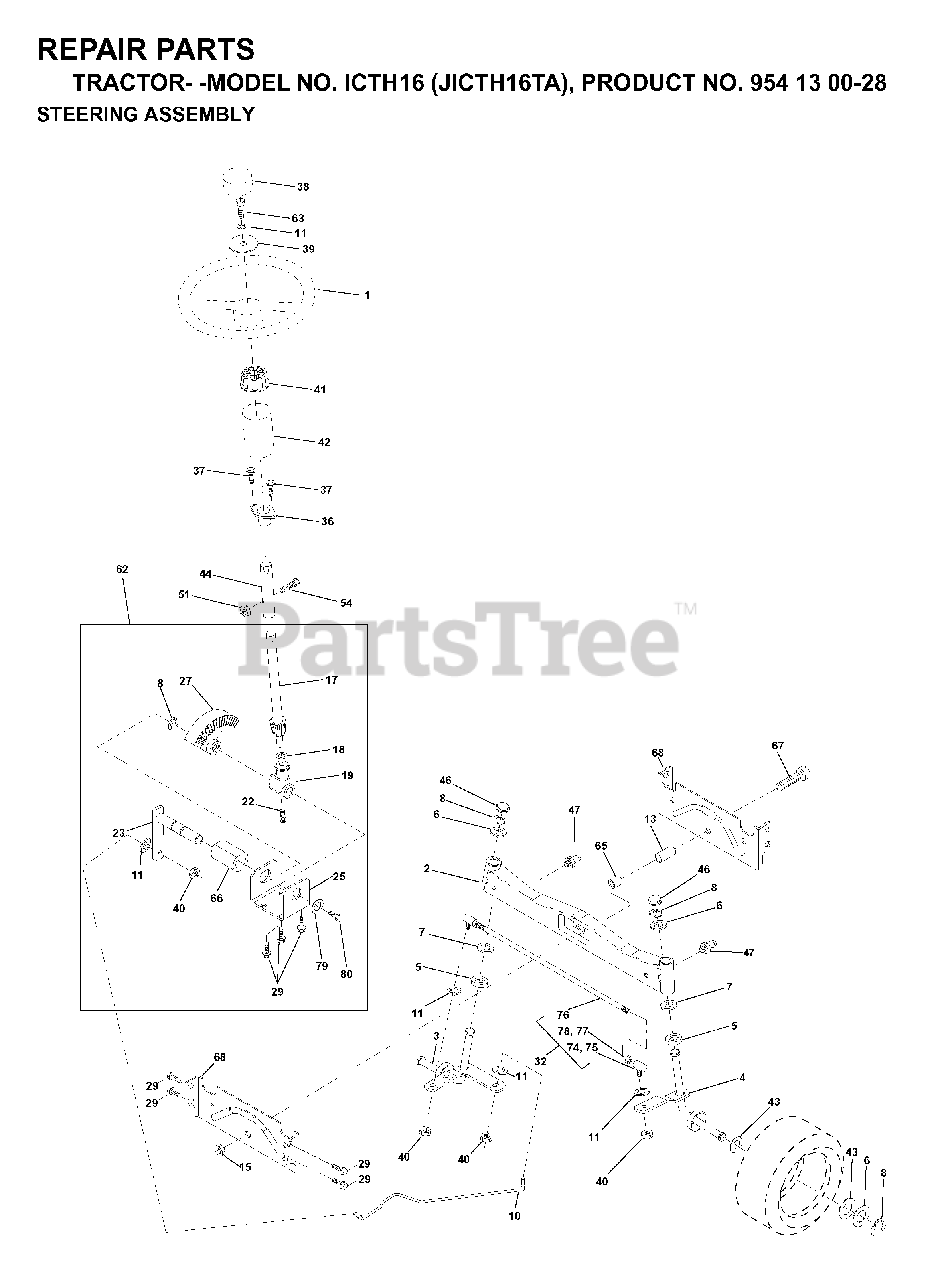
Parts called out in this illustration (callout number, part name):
2	FRONT AXLE ASSY
3	SPINDLE ASM LH
4	SPINDLE ASM RH
8	RING CLIP
10	LINK.DRAG.DROPPED.LT
11	WASHER, LOCK 3/8
13	SPACER, FRT AXLE BRNG
15	NUT-LOC,FLANGE LT
17	SHAFT ASM STEERING
18	THRUST WASHER
19	STEERING SHAFT SUPPORT
22	SCREW.HX.WSH.HD
23	SHAFT ASSY PITTMAN
25	BRACKET STEERING
27	GEAR.SECTOR
29	SCREW
32	ROD ASSY/TIE BALL
36	BUSHING, STEERING
38	RP INSERT
39	WASHER T
40	GRIPCO NUT
41	ADAPTER LT
42	STEERING BOOT, GRAY
44	EXT SHAFT STEERING
46	CAP.SPINDLE
47	ZERK M
51	NUT.71038.31-18.HEX.NYLOCK
54	BOLT.5/16-18X1-1/4 FULL.THREAD
62	STEERING KIT
65	SPACER AXLE
66	BEARING ARM
67	BOLT.HEX.FINISHED.5/8
68	AXLE, BRACE
74	JOINT
76	TIE ROD
80	BOLT.HX.NYLON3/8-16X
